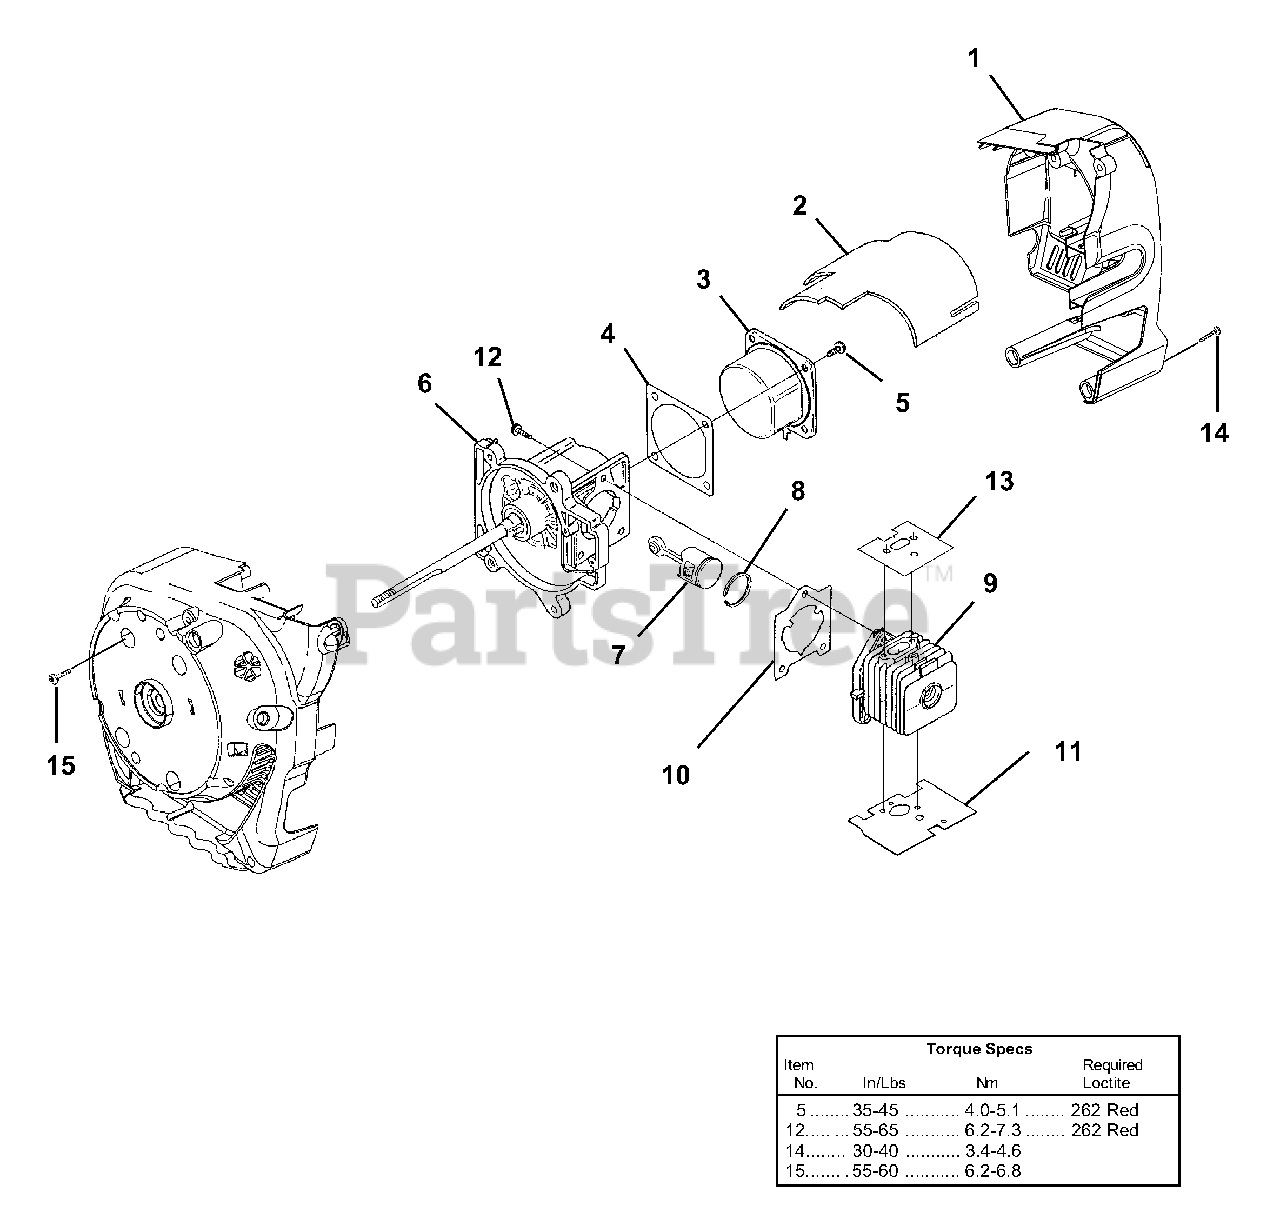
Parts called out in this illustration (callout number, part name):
1	Shroud
2	Heat Shield, Muffler
3	Crankcase Cover Kit
4	Gasket, C/Case
5	Screw, Sems (10-24 x .560)
6	Short Block (Svc) (25cc)
7	Piston & Rod (25cc)
8	Piston Ring (25cc)
9	Cylinder Kit (25cc)
10	Gasket, Cylinder
11	Gasket, Heat Dam
12	Screw, Sems (12-24 x 3/4)
13	Gasket, Muffler
14	Screw, Thread Forming (10-14 x 7/8)
15	Taptite, Truss (10-24 x 3/4)
